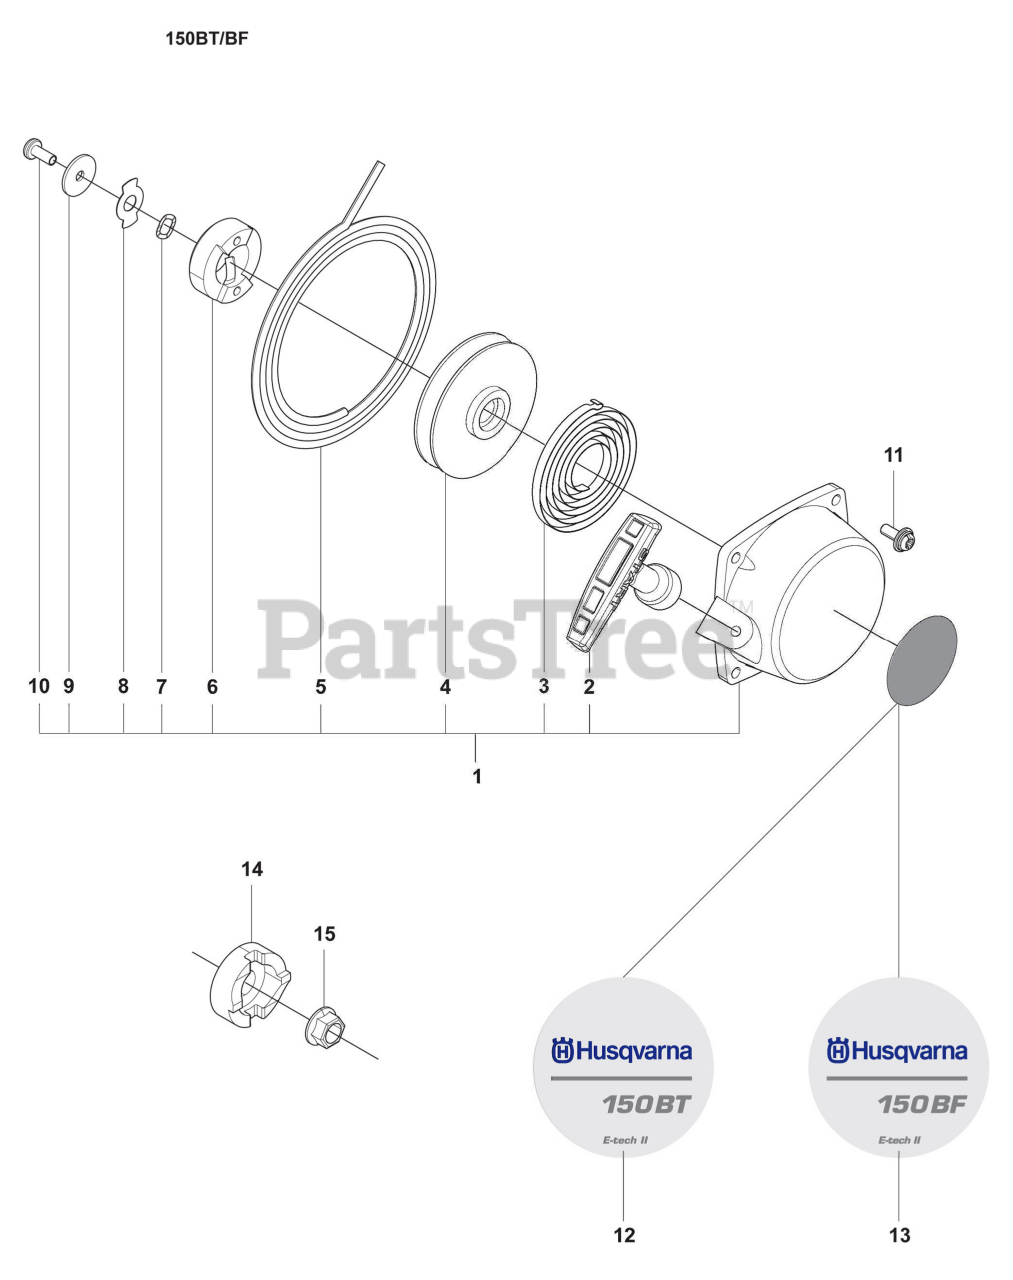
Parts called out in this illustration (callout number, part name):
1	Recoil Starter Assembly
4	Starter Pulley
6	Starter Pawl
8	RETAINER
9	WASHER
12A	Decal
12B	DECAL
13	Pulley
14	Nut
